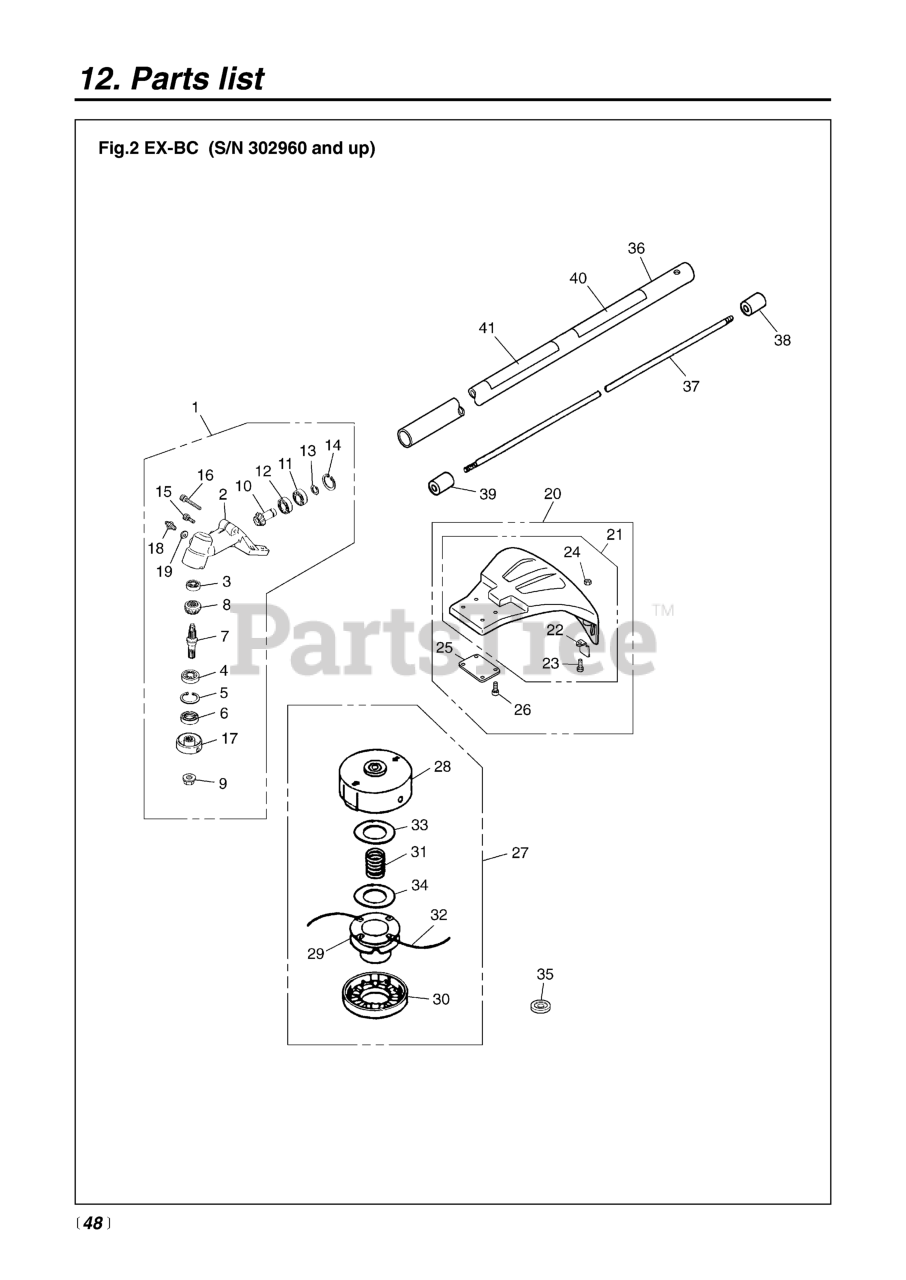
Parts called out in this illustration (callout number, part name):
1	GEARCASE ASSY (RPLS -13000)
2	GEARCASE
5	RING, SNAP, M26 X 1.2
6	SEAL, OIL
7	SHAFT
8	GEAR
9	NUT
10	PINION
14	RING, SNAP, M24 x 1.2
15	BOLT, M5 X 10
16	BOLT
17	HOLDER (A)
18	FITTING, GREASE
19	WASHER, M6 X .8
20	GUARD ASSY (RPLS -24000)
21	GUARD COMP (RPLS. -24100)
22	BLADE (RPLS T3002-24120)
23	SCREW
24	NUT
25	PLATE
26	BOLT (USE 3310-31720)
27	4
29	HOLDER, CORD (RPLS -15141)
30	COVER (RPLS -15130)
31	SPRING (RPLS -99161)
32	CORD
33	PLATE, LARGE
34	PLATE, SMALL
35	HOLDER (B)
36	PIPE COMPLETE
37	SHAFT
38	JOINT, SHAFT (RPLS -12240)
39	SPACER
40	PLATE, NAME (BC-EX)
41	PLATE, CAUTION
